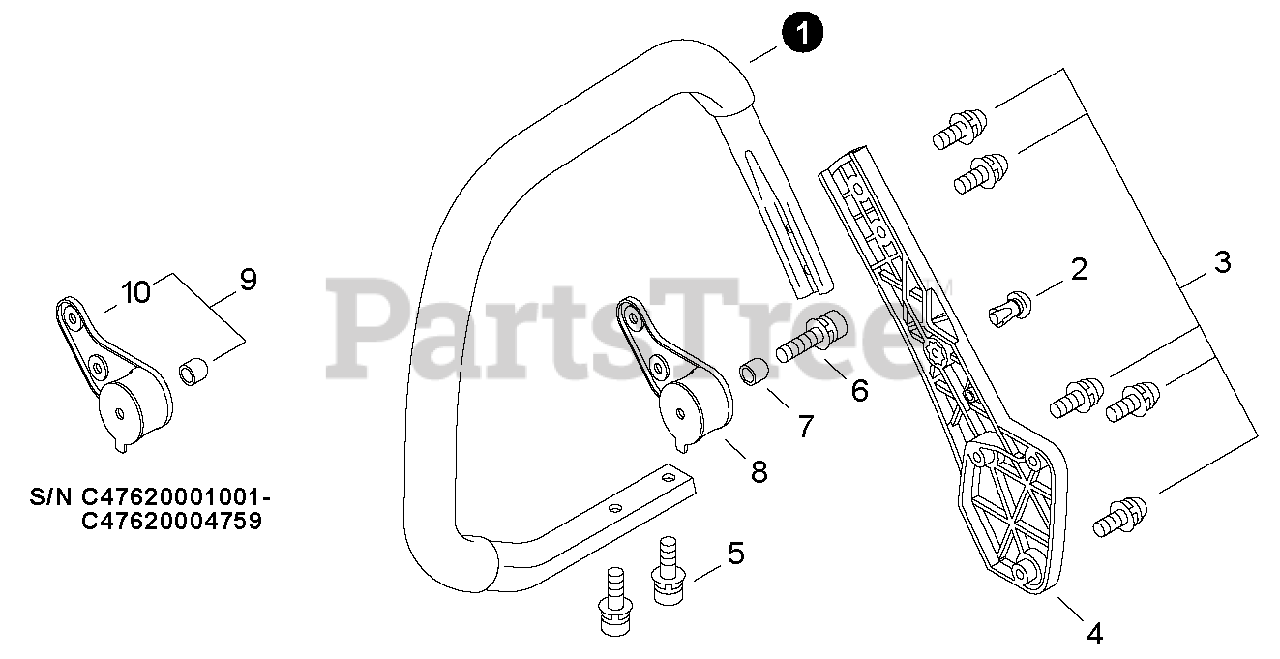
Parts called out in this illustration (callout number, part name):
1	HANDLE, FRONT
3	SCREW 5×20
4	BRACKET, HANDLE
5	BOLT 5×14
6	BOLT 5×20
7	COLLAR 5
8	CUSHION 5
9	CUSHION KIT
10	CUSHION 5
